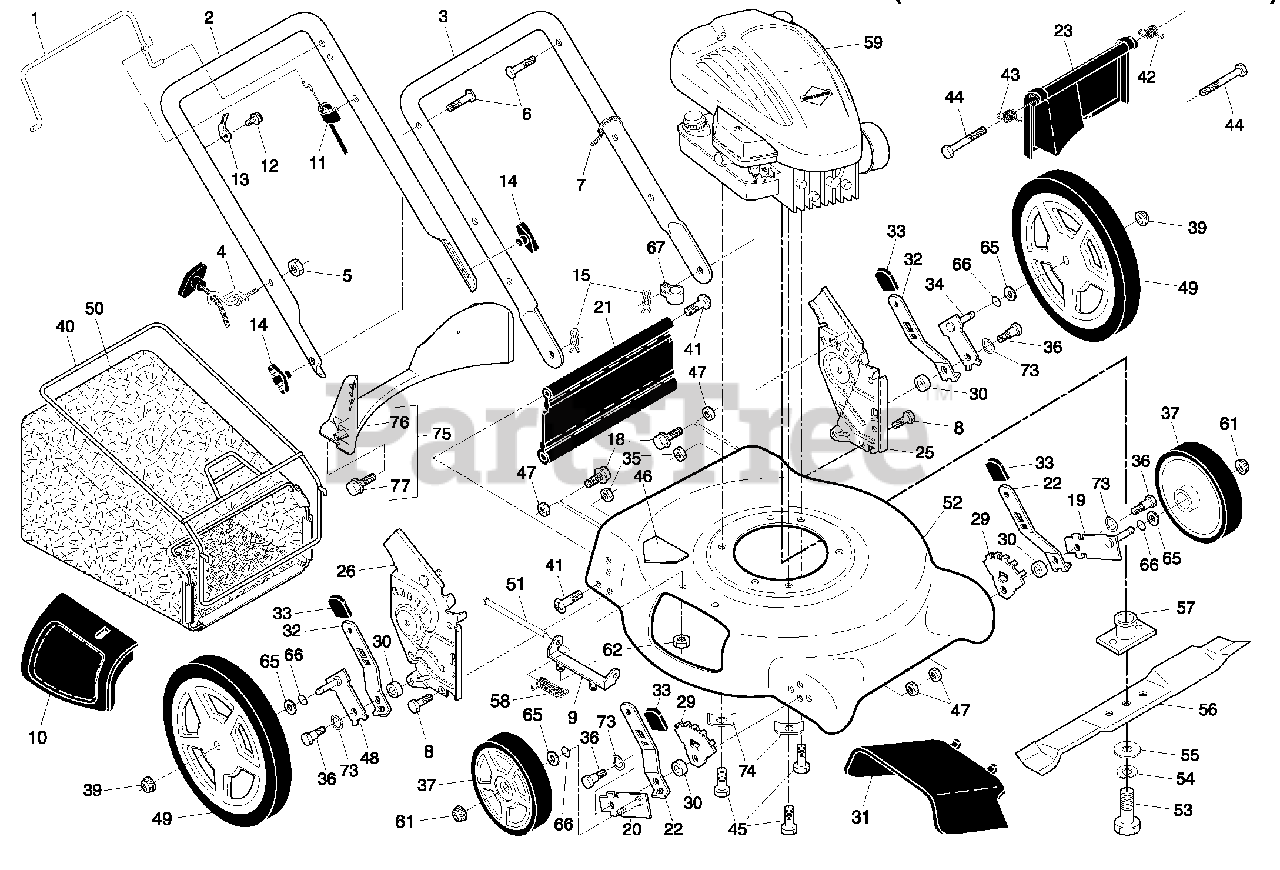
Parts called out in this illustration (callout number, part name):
1	Control Bar
2	Upper Handle
3	Lower Handle
4	Rope Guide
6	Handle Bolt
7	Wire Tie
8	Bolt, Hex Head 5/16-18 x 3/4
11	Engine Zone Control Cable
12	Hex Washer Head Screw #10-24 x 1/2
13	Up-Stop Bracket
14	Handle Knob
15	Hairpin Cotter
18	Screw
19	Axle Arm Assembly, Front, LH
20	Axle Arm Assembly, Front, RH
21	Rear Skirt
22	Selector Spring, Front
23	Rear Door Assembly
25	Handle Bracket Assembly, LH
26	Handle Bracket Assembly, RH
28	Wheel Adjusting Bracket, Front, LH
29	Wheel Adjusting Bracket, Front, RH
30	Spacer
32	Selector Spring, Rear
33	Selector Knob
34	Axle Arm Assembly, Rear, LH
35	Nut, Hex
36	Shoulder Bolt 5/16-18
37	Wheel & Tire Assembly, Front 7 x 1-3/4
39	Nut, Hex
40	Frame, Grassbag
41	Screw, Hinge
42	Spring, LH
43	Spring, RH
44	Bolt, Rear Door
45	Hex Head Thread Rolling Screw 3/8-16 x 1
46	Danger Decal
47	Locknut, Hex 5/16-18
48	Axle Arm Assembly, Rear, RH
49	Wheel & Tire Assembly, Rear 12 x 1-3/4
50	Grassbag
52	Housing Assembly
53	Hex Head Screw 3/8-24 x 1-3/8 Grade 8
54	Helical Lockwasher
55	Hardened Washer
56	21" Blade
57	Blade Adapter
61	Flanged Locknut
65	Washer, Flat
66	O-Ring
67	Clip, Cable
73	Washer, Curved, Cylindrical
74	Washer, Special, Engine
75	Kit, Rear Baffle
76	Baffl e, Rear
77	Screw, Rear Baffle
77	Operator's Manual, English
77	Operator's Manual, French
77	Repair Parts Manual
